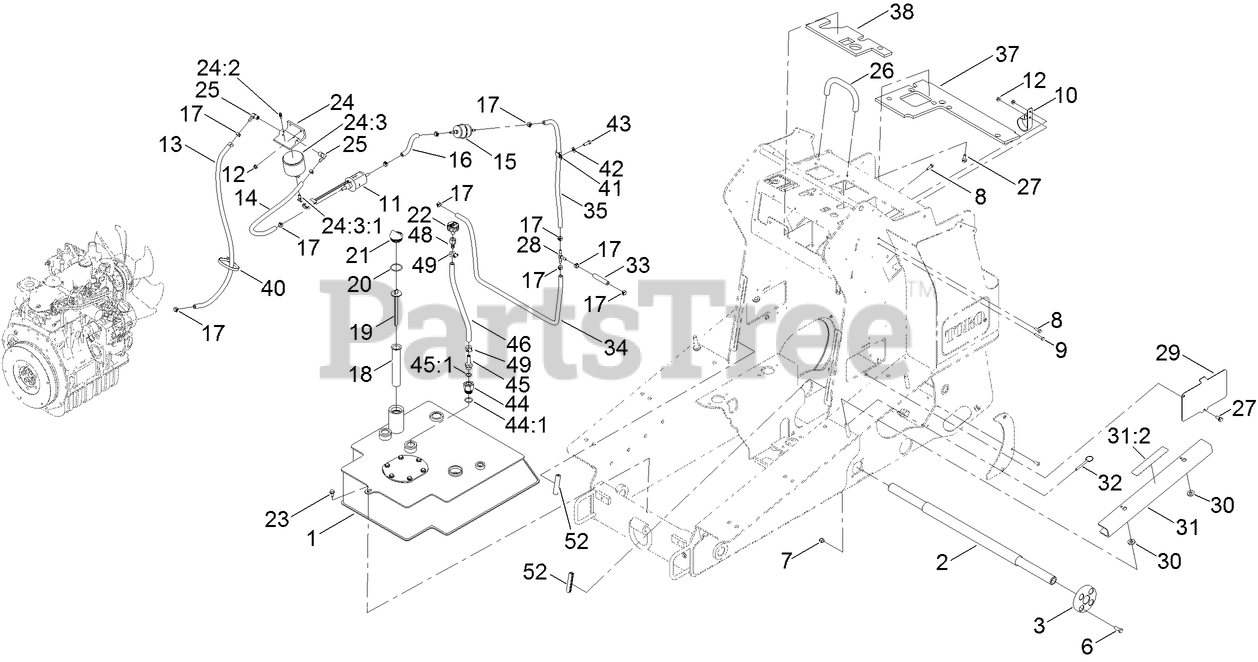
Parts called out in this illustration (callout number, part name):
1	TANK-HYD
2	SHAFT-TRACK
3	HUB-SHAFT
6	SCREW-HH
7	NUT-LOCK, NI
8	SCREW-HH
9	SCREW-HH
10	BRACKET-PUMP, FUEL
11	PUMP-FUEL
12	NUT-HF
13	HOSE-FUEL
14	HOSE-FUEL
15	FILTER-INLINE
16	HOSE-FUEL
17	CLAMP-HOSE
18	FILTER-SCREEN
19	DIPSTICK
20	O-RING
21	PLUG-PLASTIC
22	BREATHER
23	SCREW-THD ROLL, HWH
24	FILTER HEAD ASM
24:2	VENT-AIR
24:3	ELEMENT-SPIN ON
24:3:1	VALVE-DRAIN
25	FITTING-HYD, 90
26	BAR-REFERENCE
27	SCREW-HHF
28	FITTING-TEE, BARBED
29	PLATE-COVER, ACCESS
30	WASHER-NEOPRENE
31	ARM-LOCKING
31:2	DECAL-DANGER
32	PIN-COTTERLESS
33	HOSE-FUEL
34	HOSE-FUEL
35	HOSE-FUEL
37	FOAM-HEAT SHIELD
38	FOAM-HEAT SHIELD
40	TIE-CABLE
41	CLAMP-R
42	WASHER-FLAT
43	SCREW-HH
44	FITTING-STRAIGHT
44:1	O-RING
45	FITTING-STR
45:1	O-RING
48	FITTING-FEMALE, BARBED
49	CLAMP-HOSE
